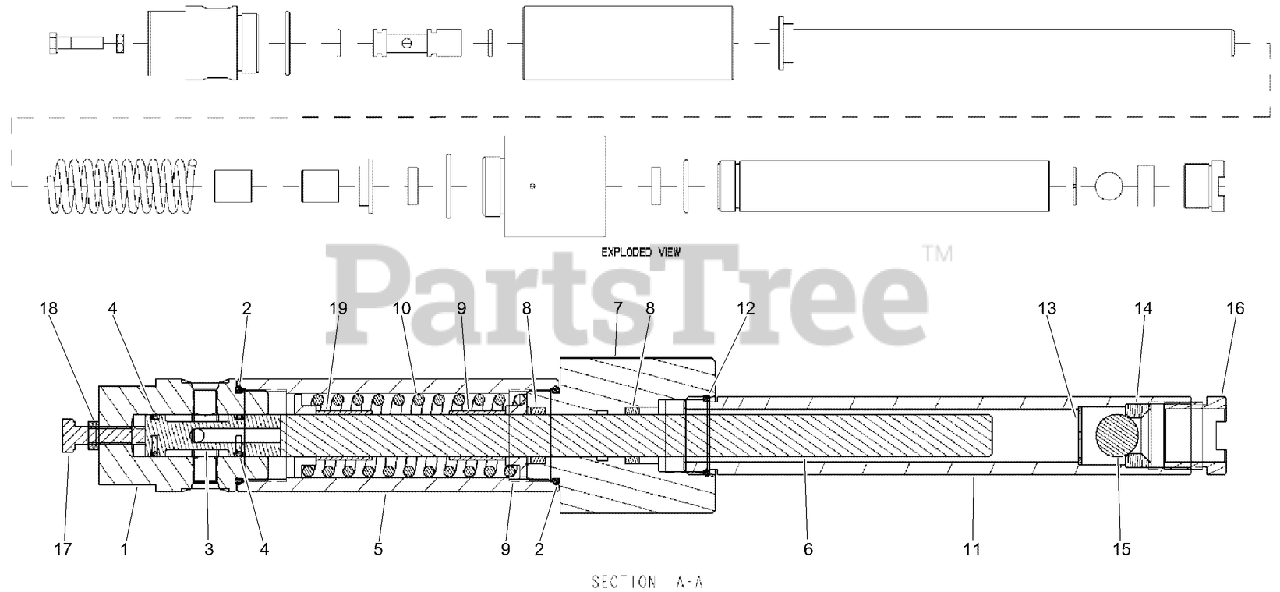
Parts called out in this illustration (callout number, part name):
1	CAP - Cylinder
2	SEAL-O RING
3	SPOOL-ADJUSTING
5	BARREL - Cylinder
6	PLUNGER
7	BODY - Pump
8	SEAL-DEEP
9	GUIDE-ROD
10	SPRING
11	BARREL-PUMP
12	SEAL-O RING
13	CLIP-RETAINER
14	VALVE-SEAT
15	BALL-STEEL, STAINLESS
16	TUBE-INLET
17	BOLT - Hex Hd .312 x 1.25 GR8 PHC
18	NUT - Hex Jam 5/16-18 GR5 ZND
19	BEARING - Sleeve, Bronze
